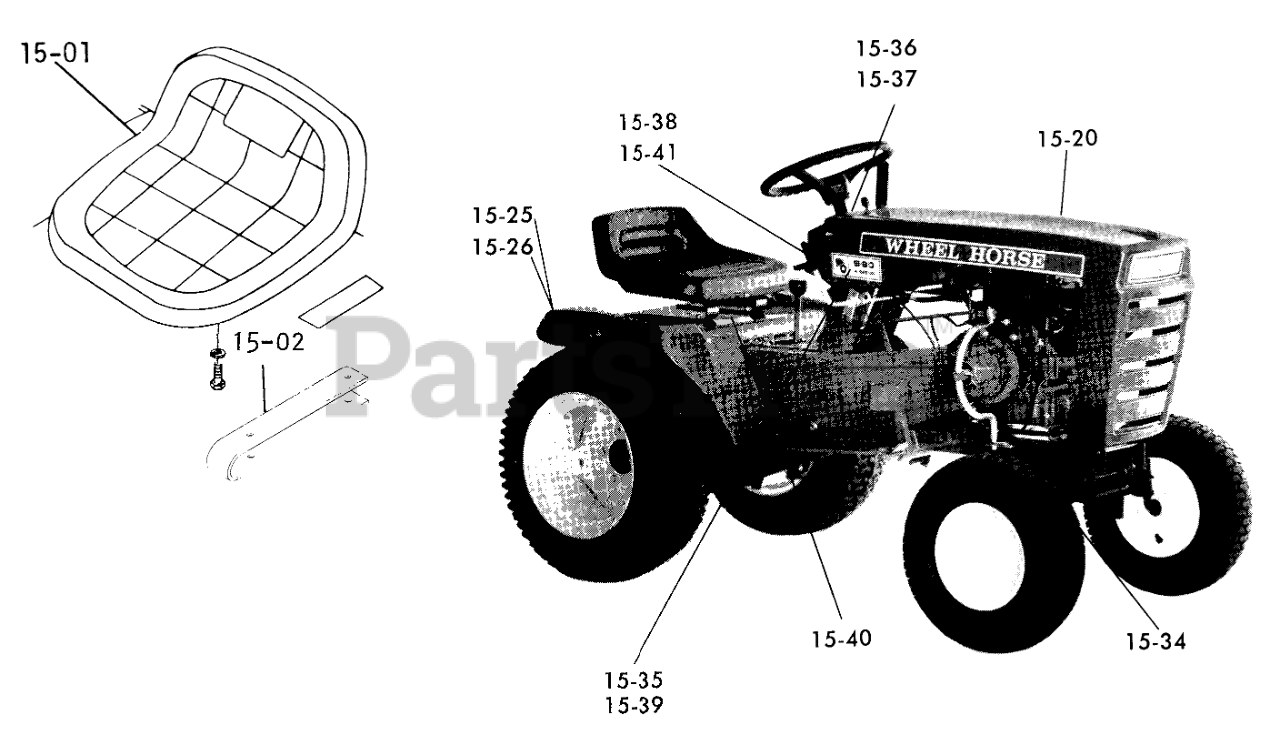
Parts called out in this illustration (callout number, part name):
15-01	Seat
15-02	Spring
15-20	Decal
15-25	DECAL-WHEEL HORSE
15-26	Reflector
15-34	Washer
15-35	Decal-B-80
15-36	Washer
15-37	Decal-Read Manual
15-38	DECAL-HAND LIFT
15-39	DECAL-4 SPD SHIFT
15-40	Decal-Park Brake
15-41	Decal
